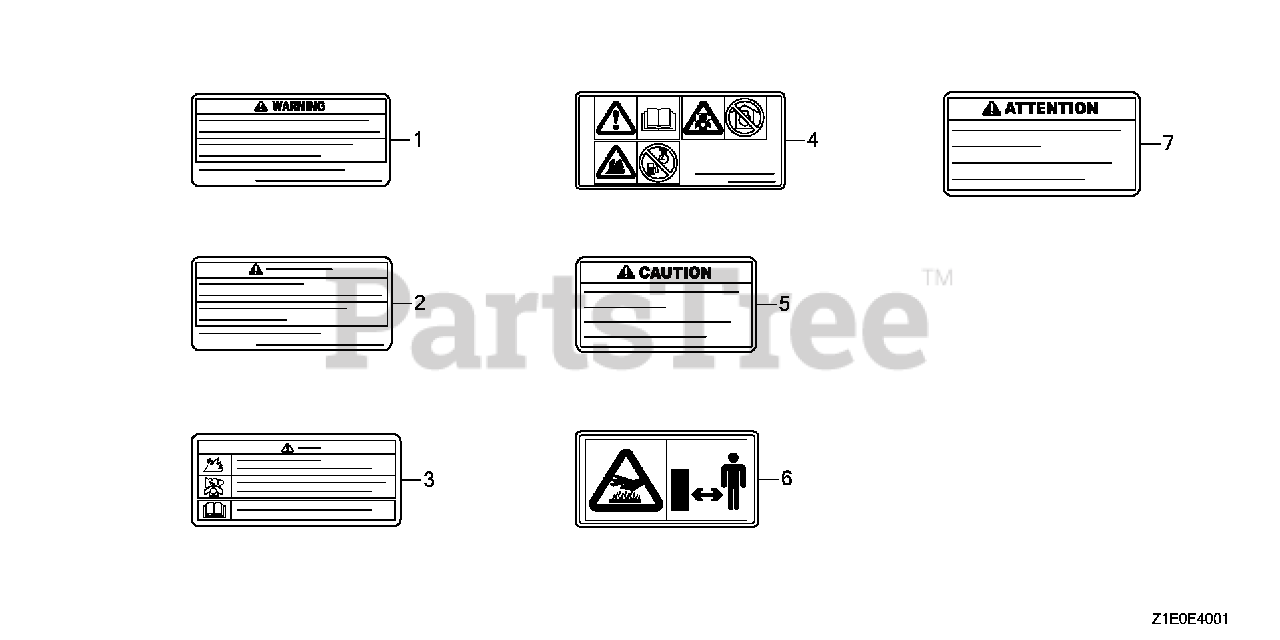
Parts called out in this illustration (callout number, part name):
2	MARK, OPERATOR CAUTION (FRENCH)(MADE IN THAI)
4	MARK, OPERATOR CAUTION (PICTOGRAPH)
6	MARK, EX. CAUTION (PICTOGRAPH)
7	MARK, EX. CAUTION (FRENCH)
